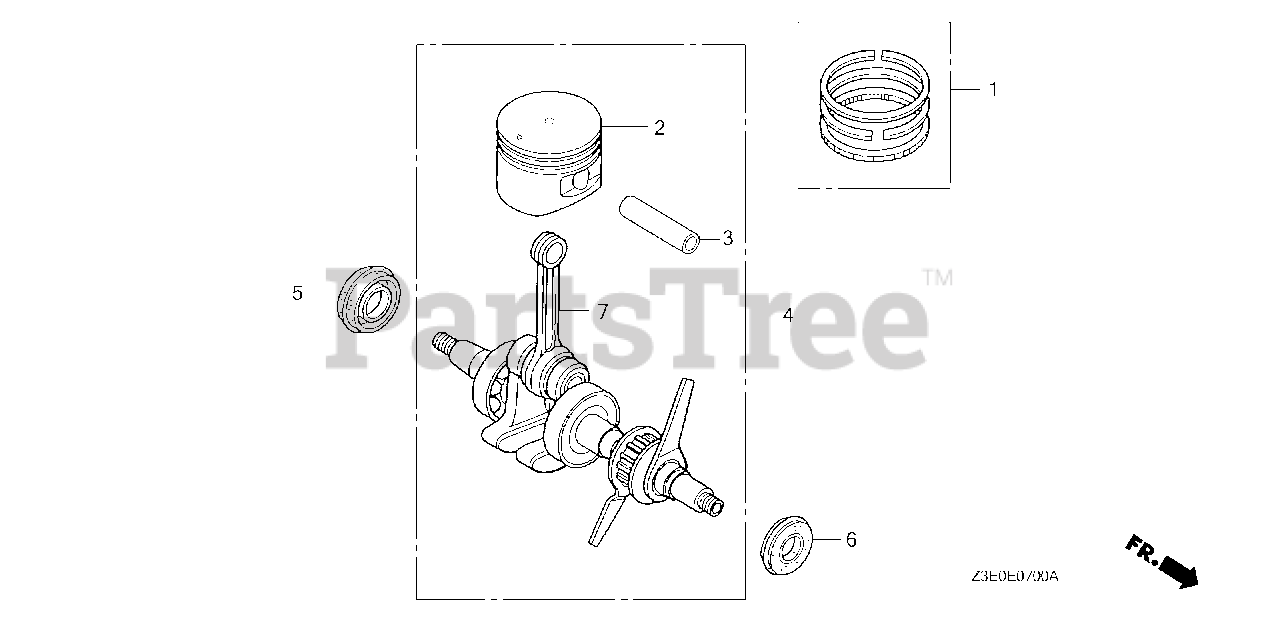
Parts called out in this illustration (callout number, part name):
1	RING SET, PISTON
1	RING SET, PISTON (TPR)
2	PISTON
2	PISTON (STD)
3	PIN, PISTON
4	CRANKSHAFT
5	OIL SEAL (12X24X5)
6	OIL SEAL (10X20X5) (NA USE ALT:91212-Z3E-003)
6	OIL SEAL (10X20X5)
7	CRANKSHAFT
